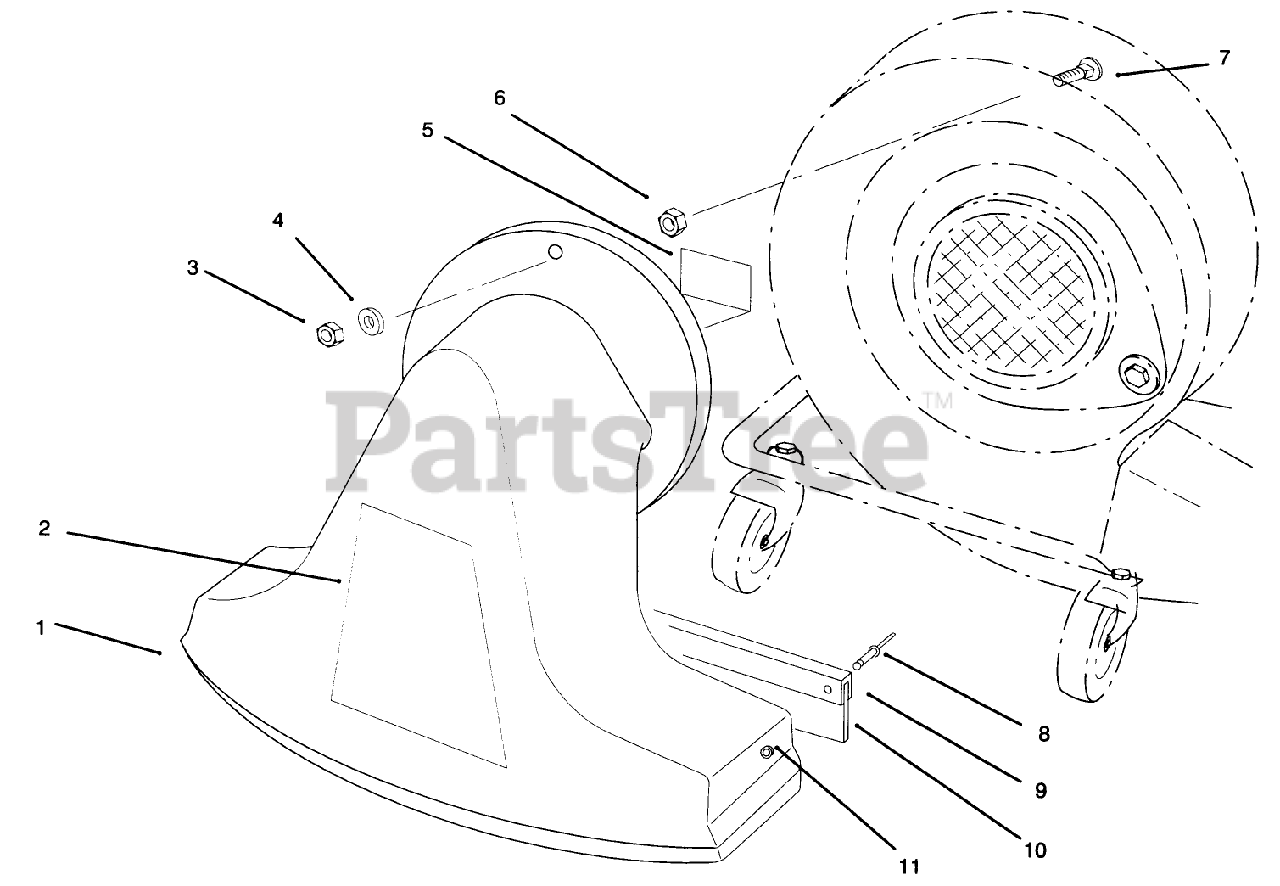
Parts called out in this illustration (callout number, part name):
1	SNOUT ASM
3	NUT-LOCK, NI
5	DECAL-CAUTION, BAG
6	NUT-FLANGE
7	BOLT-CARRAIGE
8	POP RIVET 3/16X.375LG
10	FLAP-RUBBER
11	WASHER-FLAT
